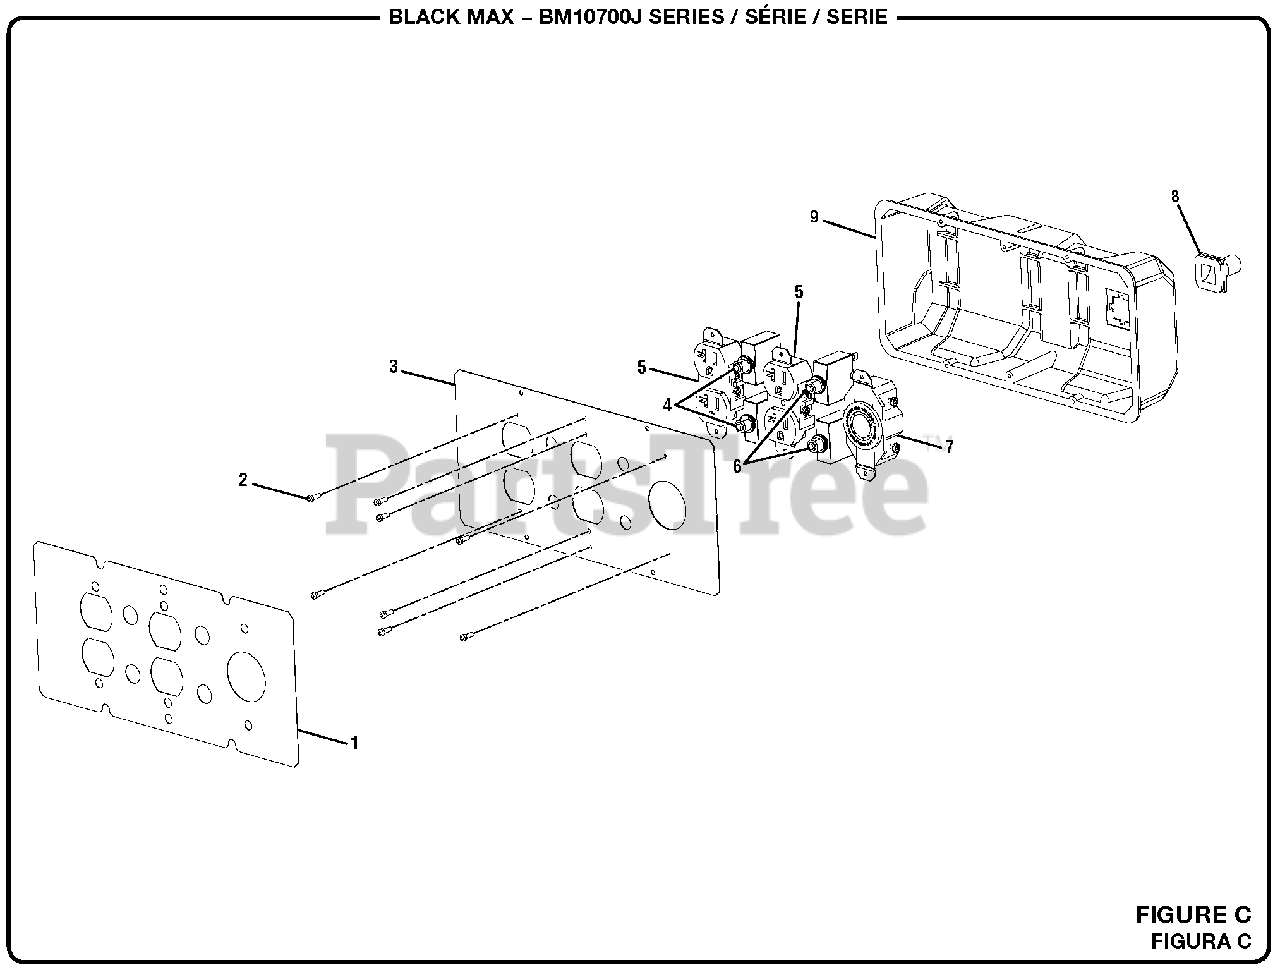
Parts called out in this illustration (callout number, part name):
1	Label (Power Outlet)
2	Screw (6-20 x 3/8 in)
3	Front Panel
4	Circuit Breaker (20 Amp, 125 Volt)
5	120 Volt Duplex Receptacle (GFCI)
6	Circuit Breaker (30 Amp)
7	Twist Lock Receptacle (120/240 Volt, 30 Amp, L14-30R)
8	Rubber Boot
9	Control Box (Back Panel)
